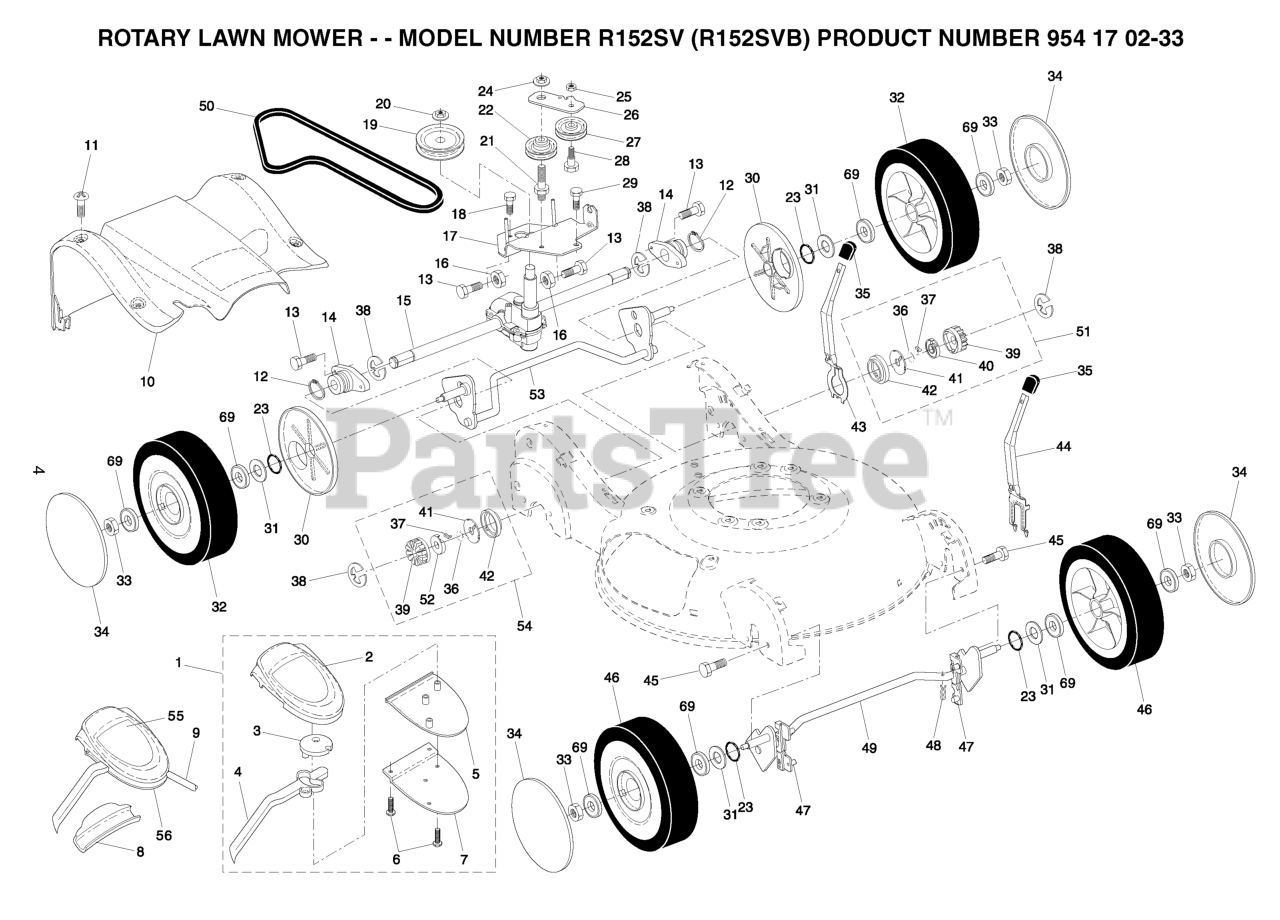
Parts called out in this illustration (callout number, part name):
1	EZ WALK CONTROL
2	COVER, DRIVE CONTROL, TOP
3	PULLEY.CAM.DRIVE.CONTROL.HV
4	LEVER, DRIVE CONTROL
5	COVER, DRIVE CONTROL BOTTOM
6	SCREW, PHILLIPS HEAD 10 X 5/8
7	BRACKET, DRIVE CONTROL
8	EZ WALK SNAP COVER PLATE
9	CABLE, DRIVE CONTROL
10	COVER ASM. DRIVE
11	SCREW
12	RETAINING RING (2 2)(3 2)
13	RP SCREW
14	BEARING.SUPPORT.ASSEM
15	TRANSMISSION.21.HI-VAC.EZ
16	NUT
17	BRACKET TRANSMISSION
19	RP PULLEY DRIVE
20	FLANGED LOCKNUT 3/8-16 ZINC
21	BOLT, IDLER
22	PULLEY ASSY
23	O-RING
24	NUT
25	NUT.CENTERLOCK.5/16-
26	BRACKET
27	IDLER PULLEY
28	SHOULDER BOLT
29	SCREW 14-20 X 5/8
30	DUST COVER, WHEEL
31	WASHER.FLAT.1/2
32	WHEEL ASM, REAR 9 X 2-1/4
33	HEX FLANGE LOCKNT
34	RB HUBCAP.3-SPOKE.SILVER
35	KNOB.SELECTOR.SPRG.H-GRY (2 2)
36	SPRING, TORSION
37	PAWL.DRIVE.21.EZ-WALK
38	E-RING 7/16 RE
39	GEAR, PINION
40	RETAINER.DRIVE.21.EZ-WALK.LT
41	DISC.DRIVE.21.EZ-WALK
42	SEAL.PINION
43	LEVER, SELECTOR, HEIGHT, REAR
44	LEVER, SELECTOR, HEIGHT, FRONT
46	WHEEL
47	BUSHING.FRONT.TORQUE.SHAFT
48	SPRING RETAINER
49	TORQUE SHAFT ASSY
50	BELT.DRIVE.EZ.WALK.HI-VAC
51	PINION ASSY, LH
52	RETAINER, DRIVE, RH
53	REAR AXLE ASSY.
54	PINION ASSY, RH
55	DECAL, DRIVE
69	BEARING.8".WHEEL
